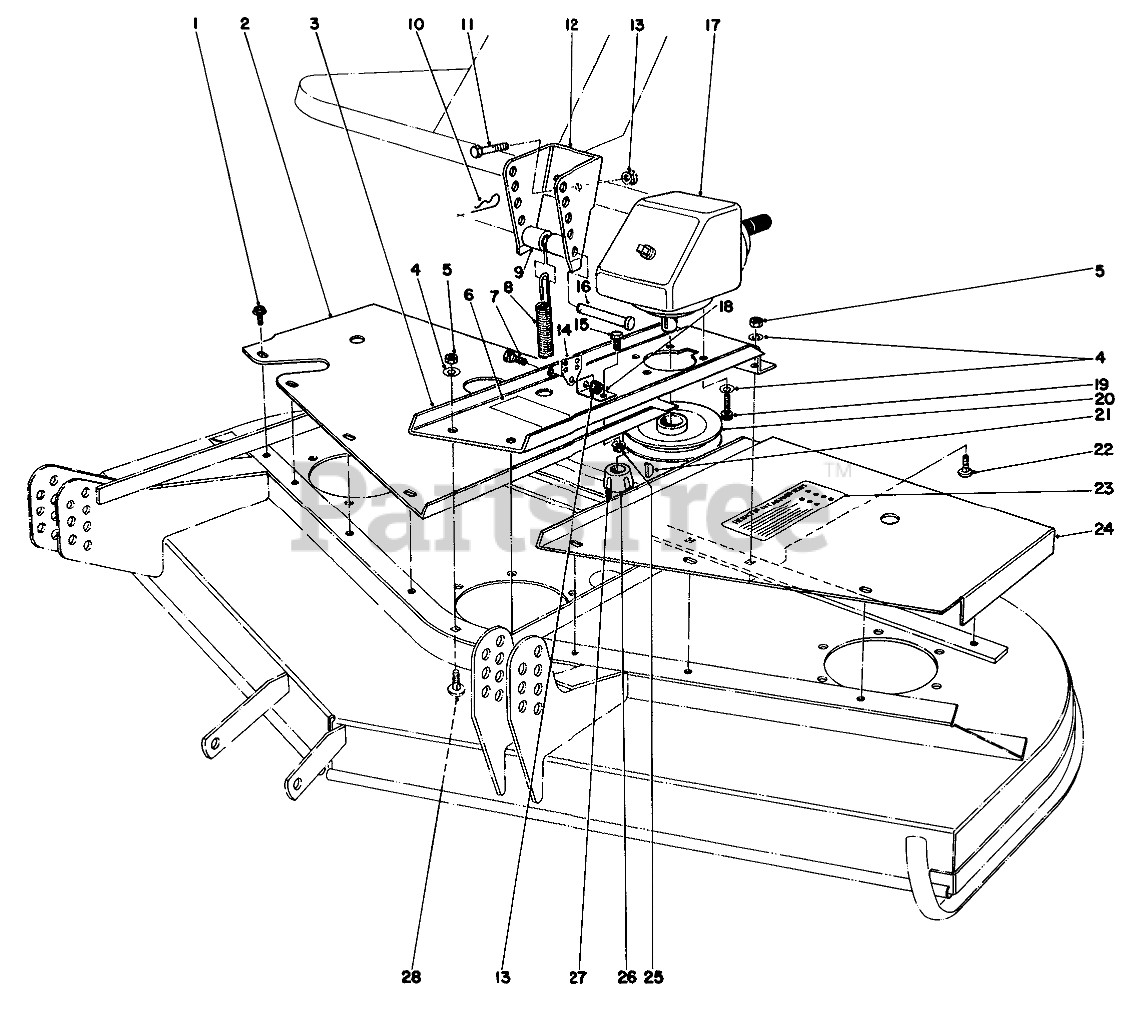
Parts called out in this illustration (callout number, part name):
1	SCREW-HHFTF
2	RH COVER WA R
3	Base-Bear Box
4	WASHER-LOCK
5	NUT-HEX
6	Decal-Caution
7	BOLT-SHOULDER
8	Spring-Extension
9	SPACER
10	PIN-HAIR
11	SCREW-HH
12	SPRING BRACKET R
13	NUT-HHF, WHIZ
14	SPRING END R
15	SCREW-HH
16	PIN-CLEVIS
17	GEAR BOX ASM
18	EXTENSION BRKT R
19	SCREW-HSH
20	PULLEY WA BO
21	KEY-WOODRUFF
22	BOLT-CARR
23	DECAL
24	LH COVER WA R
25	NUT-HF
26	BUSHING-LOCK, TAPER
27	SCREW-SET, HSH
28	SCREW-CARR
